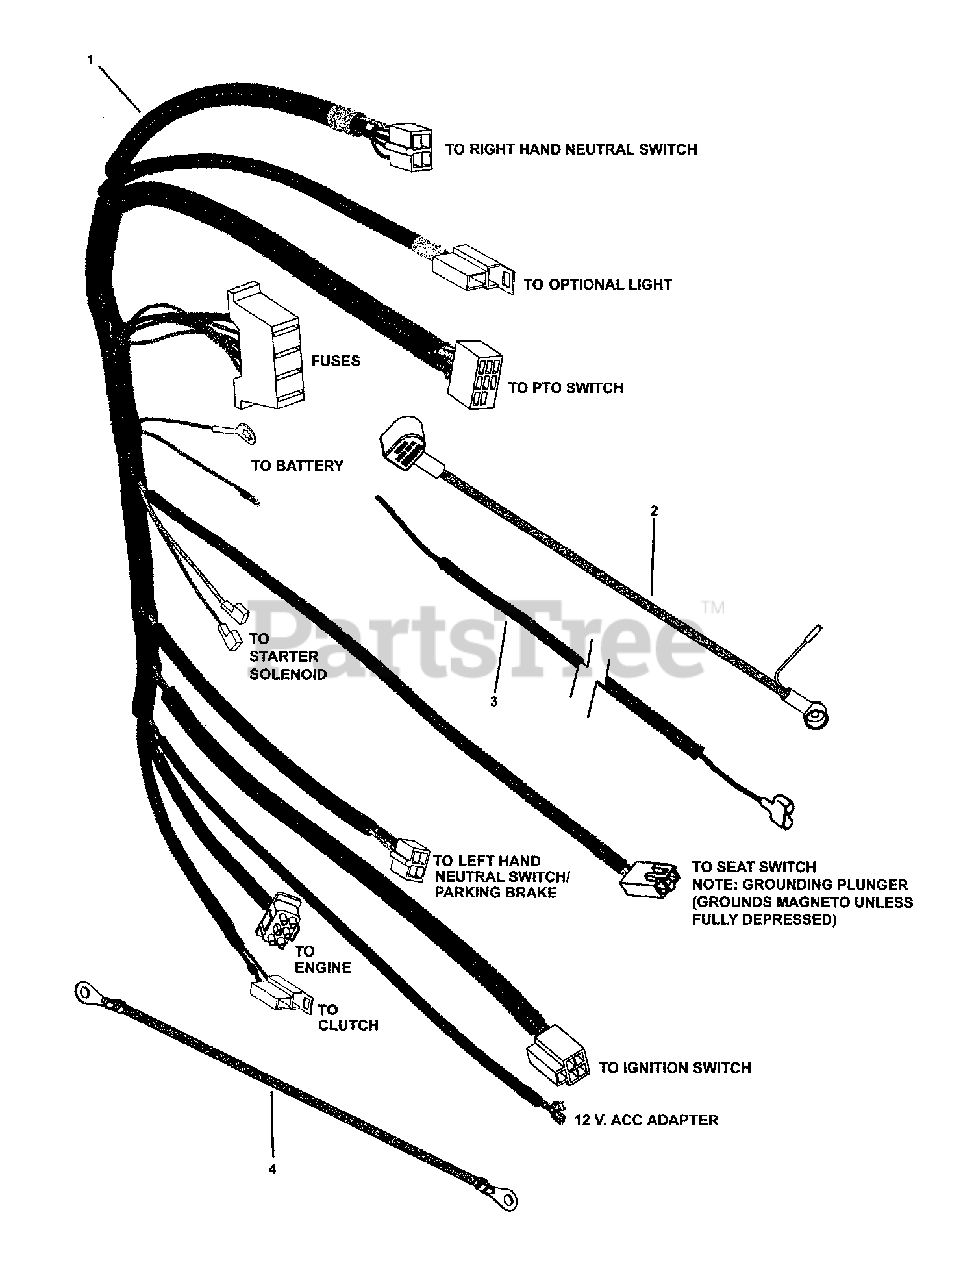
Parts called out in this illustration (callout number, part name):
1	HARNESS, RZT
2	CABLE, Battery, Positive, RZT
3	WIRING HARNESS, Hour Meter, RZT
4	WIRE, Negative, 14 IN
4	WIRE, Negative, 20-1/4 IN
